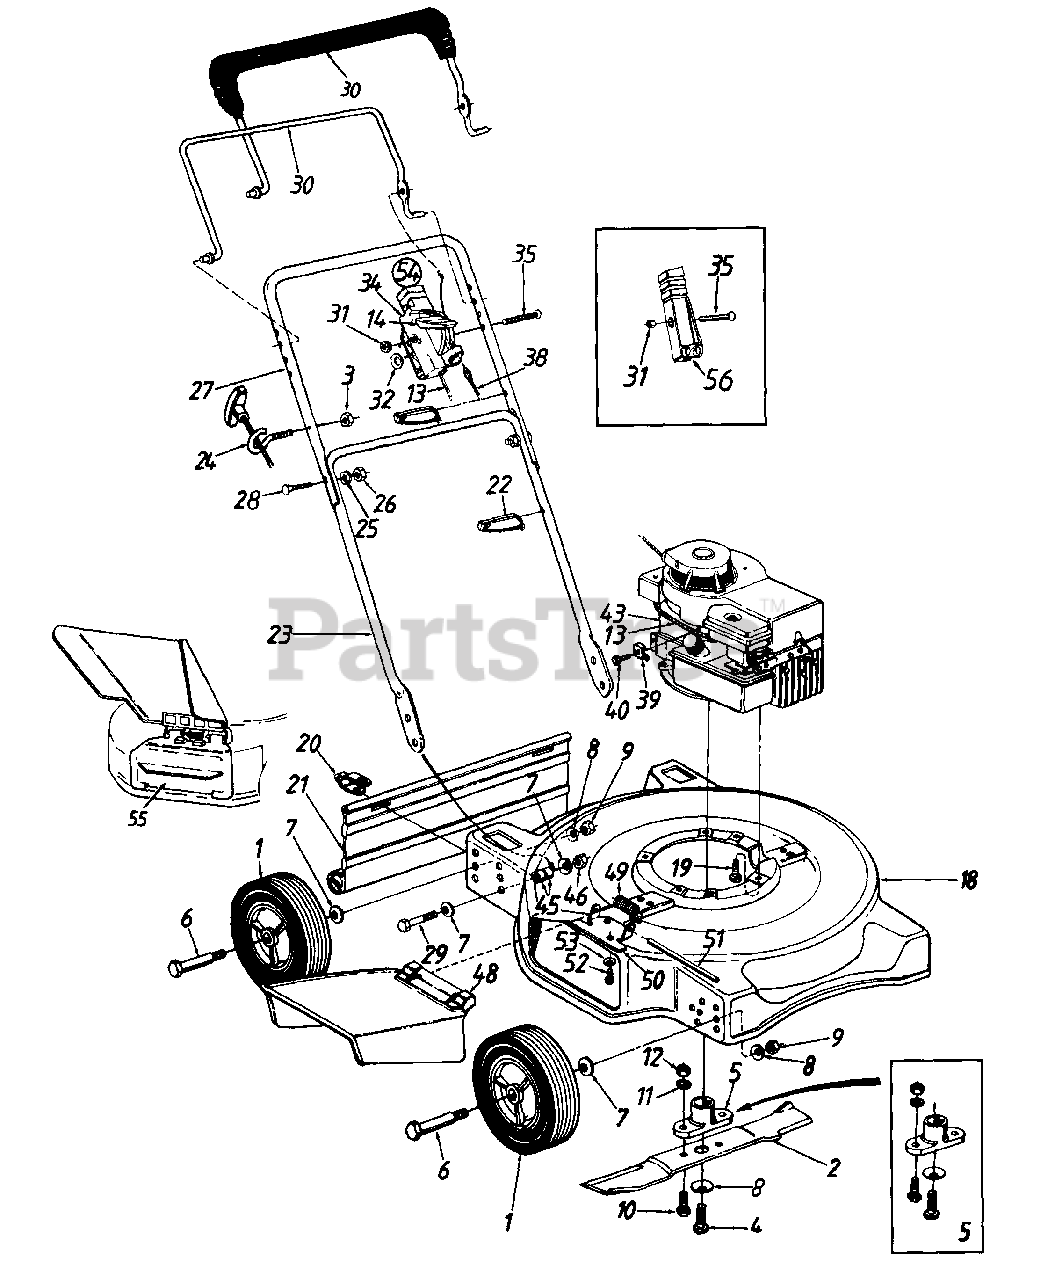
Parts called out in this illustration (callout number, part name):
1	Wheel Ass'y. Comp.
2	20" Blade
3	Hex L-Nut 1/4-20 Thd.
4	Hex Bolt 3/8-24 x 1.5" Lg.
5	Blade Adapter Kit
6	Axle Bolt
7	Bell-Wash. .380" I.D. x .88"
8	Bell-Wash. .39" I.D. x 1.13"
9	Hex Nut 3/8-16 Thd.
10	Hex Bolt 3/8-24 x 1" Lg.
11	L-Wash. 3/8" I.D.
12	Hex Nut 3/8-24 Thd.
13	Throttle Wire 51" Lg.
14	Throttle Lever
18	20" Deck Ass'y.
19	Hex Wash. Hd. Scr. 3/8-16 x 1" Lg.
20	Hinge Clip
21	Rear Flap
22	Cable Tie
24	Rope Guide
25	L-Wash. 5/16" I.D.
26	Hex Nut 5/16-18 Thd.
29	Hex Bolt 3/8-24 x 1.5" Lg.
31	Hex L-Nut 1/4-20 Thd.
32	Spr. Wash. .66" I.D.
34	Throttle Body
35	Oval C-Sunk Scr.
38	Control Cable
39	Casing Clamp (B & S)
40	Hex Wash. Hd. Scr. #10-32 x .62" Lg.
43	Engine
45	Spacer .391" I.D. x .375" Lg.
46	Hex L-Nut 3/8-24 Thd.
48	Chute Deflector Ass'y.
49	Torsion Spring
50	Adapter Plate
51	Hinge Pin
52	Hex Self-Tap Scr. 1/4-20 x .5"
53	Bell-Wash. 1/4" I.D.
54	Throttle Box Comp.
55	Mulching Plug
56	Control Cable Box
